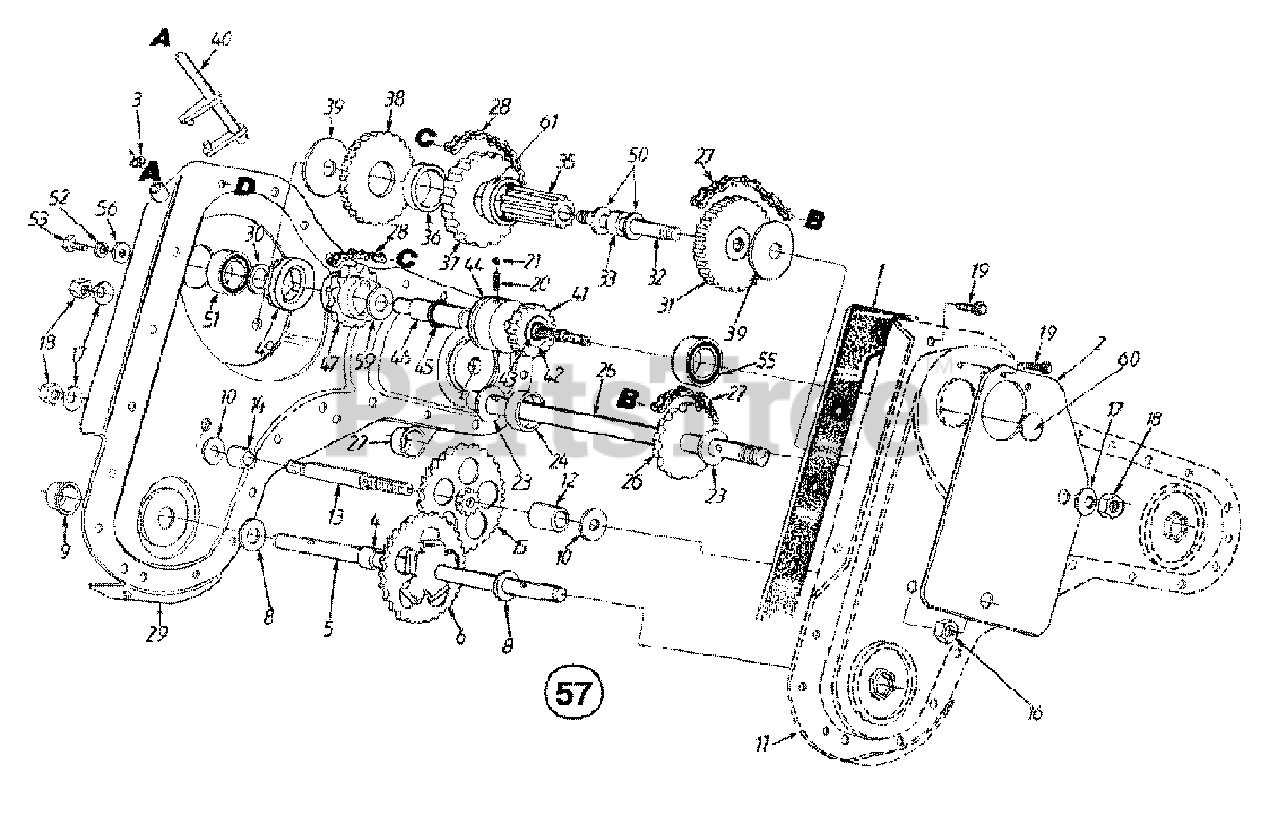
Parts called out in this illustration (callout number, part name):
1	Chain Case Gasket
4	Spacer .735" I.D. x .886" O.D.
5	Wheel Shaft
6	Spur Gear 46T
8	Fl-Wash. .76" I.D. x 1.5" O.D.
9	Shaft Seal
10	Fl-Wash. 7/16" I.D. x 1-3/8" O.D.
13	Jack Shaft 2.06" Lg.
14	Spacer .635" I.D. x 1" O.D. x .37" Thk.
15	Gear Idler Ass'y.
16	Hex Patch L-Nut 7/16-20 Thd.
17	Bell-Wash. .45" I.D. x 1" O.D.
18	Hex Nut 7/16-20 Thd.
19	Hex Wash. Hd. TT-Tap Scr. 1/4-20 x .5" Lg.
20	Spring Detent
22	Shaft Seal
23	Thrust Wash. 1.03" I.D. x 1.62"
24	Spacer 1" I.D. x 2" O.D. x .5" Thk.
26	Tine Shaft Ass'y.
27	Chain #50 5/8" Pitch x 52 Links - Endless
28	Chain - #41 1/2" Pitch x 30 Links - Endless
30	Fl-Wash. 7/16" I.D. x 1-3/8" O.D.
31	Gear and Sprocket Ass'y.
32	Jack Shaft 5" Lg.
33	Spacer .636" I.D. x .86" O.D.
35	Spur Gear 10T
36	Spacer 1.5" I.D. x 1.76" O.D.
37	Sprocket - #41 Chain
38	Reverse Gear 46T
39	Thrust Wash. .445" I.D. x 1.92"
40	Shifter Ass'y.
41	Spur Gear 17T
42	Fl-Wash. .69" I.D. x 1.06" O.D.
44	Clutch Collar
45	Retaining Ring .875" Shaft
46	Drive Shaft
47	Sprocket 11T
49	Spur Gear 16T
50	Fl-Wash. 5/8" I.D. x 1" O.D.
51	Ball Bearing .669" I.D.
52	L-Wash. 1/4" I.D.
53	Hex Bolt 1/4-20 x .62" Lg.
55	Ball Bearing
56	Fl-Wash. .281" I.D. x .875" O.D.
57	Gear Case Ass'y. Comp.
59	Fl-Wash. .88" I.D. x 1.5" O.D.
61	Spacer 1.52" I.D.
